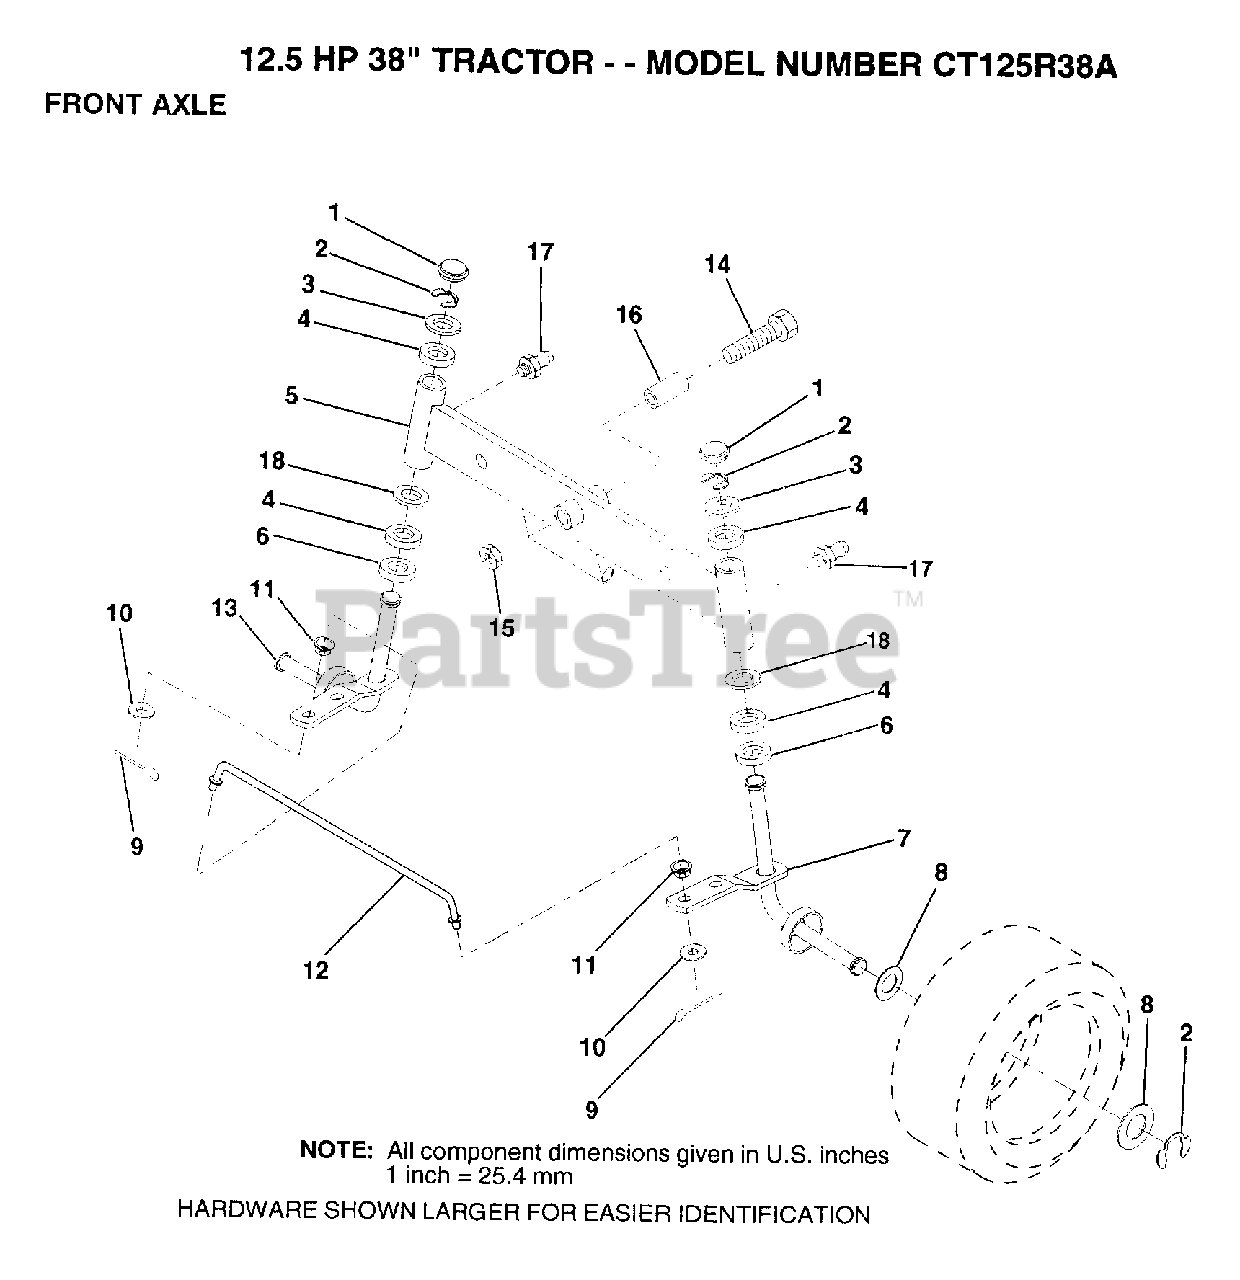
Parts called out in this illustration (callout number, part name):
1	CAP
2	RING
3	WASHER
4	COL. SRTG. BEAR.
6	WASHER .T
7	SPINDLE ASM RH
8	WASHER
9	COTTER PIN
10	WASHER
11	BUSHING.DRAGLINK
12	TIE ROD
13	SPINDLE ASM LH
14	BOLT HEX 5/8-11
15	"NUT-LOC,FLANGE LT"
16	SPACER, BEARING, FRONT AXLE
17	ZERK M
18	WASHER
